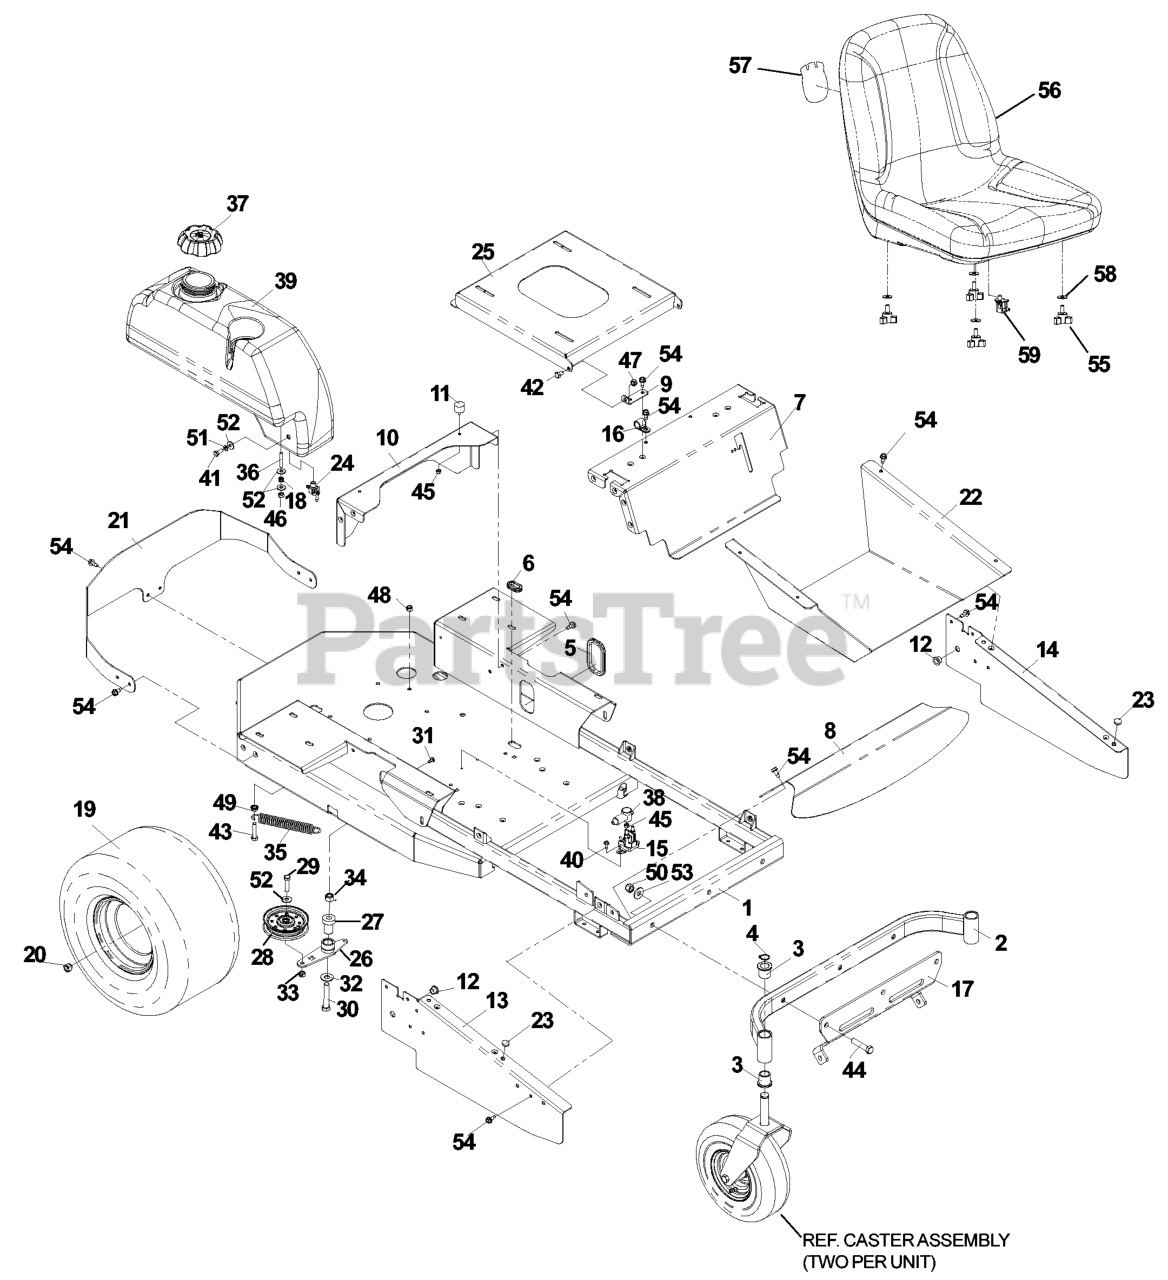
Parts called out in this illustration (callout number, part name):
1	MAINFRAME W/DECALS
2	CASTER AXLE W/BUSHING
3	BUSHING, FLANGED
4	RETAINING RING, 7/8"
6	RUBBER GROMMET
7	SEAT SUPPORT W/DECALS
8	FRONT FOOT PLATE
9	SEAT BRACKET-BLACK
10	REAR SUPPORT-ORANGE
11	STUD/PLATE MOUNT
12	BUSHING, FLANGED NYLON
13	RH FRAME SIDE-ORANGE
14	LH FRAME SIDE-ORANGE
17	STRUT MOUNT
19	TIRE ASSY
19	TIRE 18 X 9.5-8 4 PLY
19	RIM.8"X6.38".ZTR
19	VALVE STEM TR-412
20	LUG NUT 1/2F
21	REAR BUMPER-BLACK
22	FLOOR PAN-ORANGE
23	GROMMET, BUMPER
24	FUEL VALVE
25	SEAT SUPPORT W/DECALS
26	PUMP IDLER ARM WELDMENT
27	IDLER SPINDLE
28	FLAT IDLER PULLEY
29	HCS 3/8C X 1 1/2
30	HCS 1/2C X 2 3/4
31	SCREW #10 X 1/2 SELF TAPPING
32	WASHER 1/2 FLAT
33	NUT 3/8C CENTERBLOCK
34	NUT 1/2-13 HEX NYLOC ZD
36	STUD, 5/16C
37	FUEL CAP
39	LEFT TANK W/CUP HOLDER
40	SCREW 1/4 X 5/8
41	HCS 5/16C X 3/4
42	BOLT .375 X .5
43	HCS 3/8C X 2 1/4
44	HEX SCREW-.5C X 2.25
45	NUT.1/4-20.HEX.NYLOC.ZD
46	NUT 5/16 NYLOC
47	NUT 3/8C CENTERBLOCK
48	NUT 3/8-16 NYLOC
49	NUT 3/8C WHIZ
50	NUT 1/2-13 HEX NYLOC ZD
51	WASHER.LOCK.HVY.HLCL.SPR.5/16
52	WASHER 5/16 FLAT
53	WASHER 1/2 FLAT
54	BOLT 5/16-18 X 3/4
55	KNOB W/STUD
57	DECAL, CROWN H
58	WASHER 5/16 FLAT
59	SEAT SWITCH
